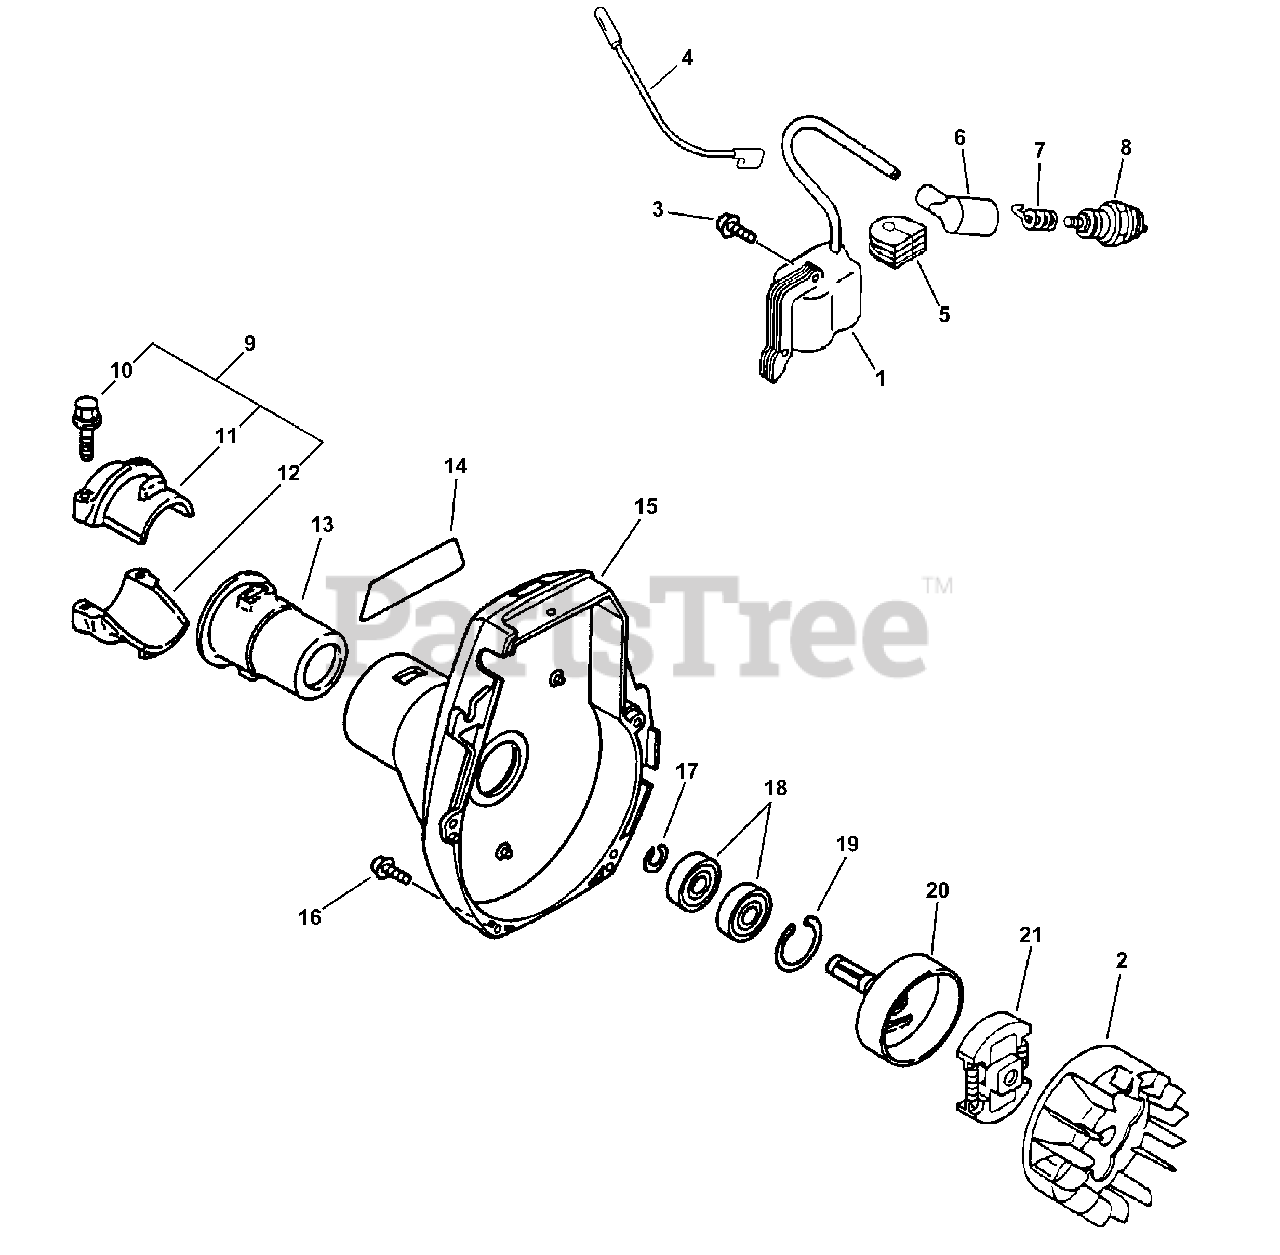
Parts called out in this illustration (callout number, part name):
1	COIL, IGNITION
2	FLYWHEEL
3	SCREW - 4X22
4	LEAD - IGNITION
6	CAP, SPARK PLUG
7	TERMINAL, SPARK PLUG CAP
8	SPARK PLUG -- BPM-7A
9	MAIN PIPE CLAMP KIT
10	BOLT - 5X25
11	CLAMP, MAIN PIPE - UPPER
12	CLAMP, MAIN PIPE - LOWER
14	LABEL - MODEL SRM-2100
14	LABEL - MODEL SRM-2110
15	CASE, FAN
16	SCREW - 4X16
17	RING, RETAINING - 12
18	BEARING, BALL - 6001
19	RING, RETAINING - 28
20	DRUM, CLUTCH
21	CLUTCH ASSY
